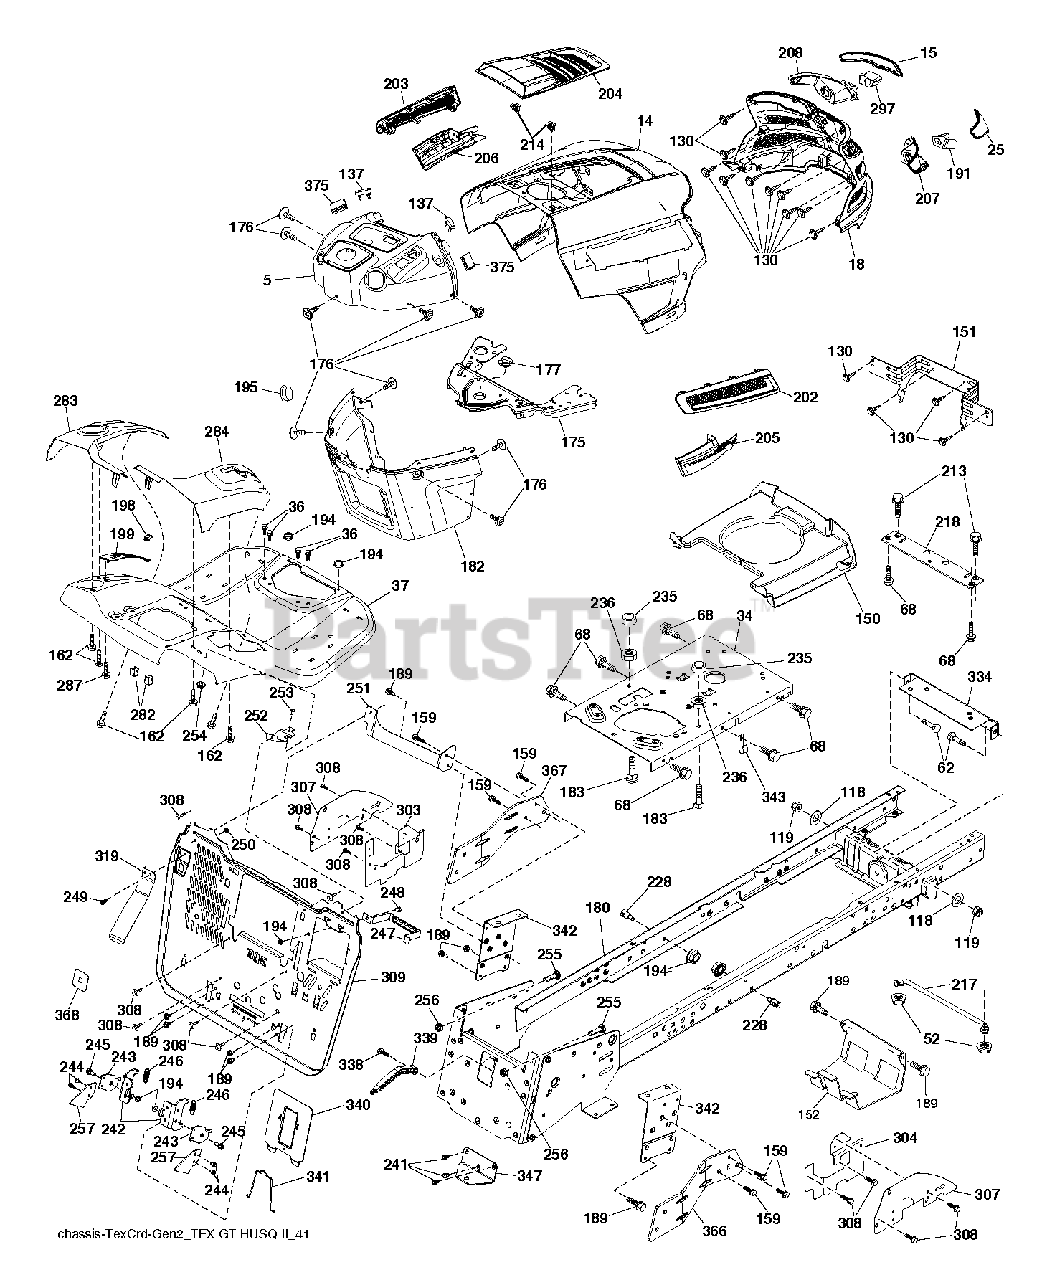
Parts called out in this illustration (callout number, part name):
5	DASH.W/O.BUMPERS.RS.SM.M.CH498
14	HOOD.ASM.HUSQVARNA.GT.TEX.ORAN
15	LENS.HEADLIGHT.LH.GTII.2011
18	GRILLE.SUBSTRATE.2011.
25	LENS.HEADLIGHT.RH.GTII.2011
34	PLATE.ENGINE.10GA.CRD.GENII
36	SCREW 5/16"
37	FENDER.TEX.SRD.CRD.BASE
52	LOCKNUT
62	BOLT D
68	SCREW LT
118	WASHER
130	SCREW.#10 X 0.750.BOS
137	BUMPER DASH
150	AIR.DUCT.GTV.BLACK
151	BRACKET.PIVOT.HOOD.GT.HUSQ.II
152	SHIELD.BROWNING.W/TEX
159	SCREW, 3/8-16X3/4
162	SCREW.HI-LO.CONSOLE
175	PLATE.CROSSMEMBER.HUSQ
176	SCREW.#10-24X5/8.RN.QU
177	BUSHING STEERING
180	WELDMENT.CHASSIS.TEX.CRD.GEN.2
182	DASH LOWER.HUSQ.PRED NO CRUISE
183	BOLT.5/16-18X1-1/4 FULL THD
189	SCREW
191	INSERT.REFLECTIVE.RH.HUSQ.GTII
194	NUT LOCK HEX FLANGE 5/16-18
195	PLUG.HOLE.DASH.LOWER.12V.BLK
198	INDICATOR.DECK.LIFT.RED
199	PLATE DECK LIFT
202	VENT.SIDE.RH.GT.HUSQ.II.
203	VENT.SIDE.LH.GT.HUSQ.II.498
204	VENT.TOP.ASM.HUSQ.GT2
205	SIDE.TRIM.RH.GT.HUSQ.II
206	SIDE.TRIM.LH.GT.HUSQ.II.GRAY
207	BEZEL LIGHT.RH.GT.II.MYLAR
208	BEZEL LIGHT.LH.GT.II.MYLAR
213	BOLT
214	CLIP.RETAINER.TINNER.
217	ROD.PIVOT.HOOD
218	X-PIECE.HOOD.STOP.NON/
228	STUD.FASTNER.W/ANTI-ROTATE
235	SPACER FENDER
236	NUT.CENTERLOCK.5/16-
241	SCREW 5/16-18X1
242	LATCH.BRACKET.TCRD.GEN 2.5.BAG
243	ARM.PIVOTING.TCRD.GEN2.5.BAGGE
244	SCREW
245	BOLT, SHOULDER
246	SPRING.TCRD.GEN2.5.BAGGER.EXT
247	STRAP.BATTERY.TCRD.GE
248	BOLT
249	SCREW.BUTTONHD.10-24X1/2.(2 2)
250	NUT 10-24 NYLOC
251	BRKT.TOPSPPRT.BCKPLT.
252	BRKT.TOPSPPRT.BCKPLT.RH.CRD2.5
253	BOLT
254	NUT T
255	BOLT.CROSSDRILLED.381
256	Hex Nut, 3/8-16
257	LATCH.BAGGER.TEXCRD2.5
282	CLIP.RETAINER.CONSOLE.LT.HUSQ
283	CONSOLE.DECKLIFT.CRDII.498
284	CONSOLE.PEDAL.HYDRO
287	SCREW 1/4X20
297	INSERT.REFLECTIVE.LH.HUSQ.GTII
303	SHIELD.LWR.LH.LT.30"CRDSRD.PNT
304	SHIELD.LWR.RH.LT30DECK.PNT.BLK
307	SHIELD.UPPER.CRD.SRD.ISO
308	BOLT, 5/16-18 X 1 3/4
309	BACKPLATE.TEXCRD2.5.B
319	LEVER.BAG.CRDII.ANTIROTATION
334	BRACKET.ENGINE
338	BOLT BOLT SHOULDER
339	LEVER LEVER BAGGER
340	BATTERY.DOOR.TCRD.GEN
341	LATCH.BATTERY.DOOR.TC
342	SUPPORT SUPPORT FENDER
343	CLIP CLIP
347	HITCH HITCH TOW TEX CRD GEN 2
366	BRACKET.RH.FRONT.BAGGER.BLACK
367	BRACKET.LH.FRONT.BAGGER.BLACK
368	FULL.LEVER.BAGGER.TEX.CRD
375	BUMPER CLIP-ON. DASH 1"
